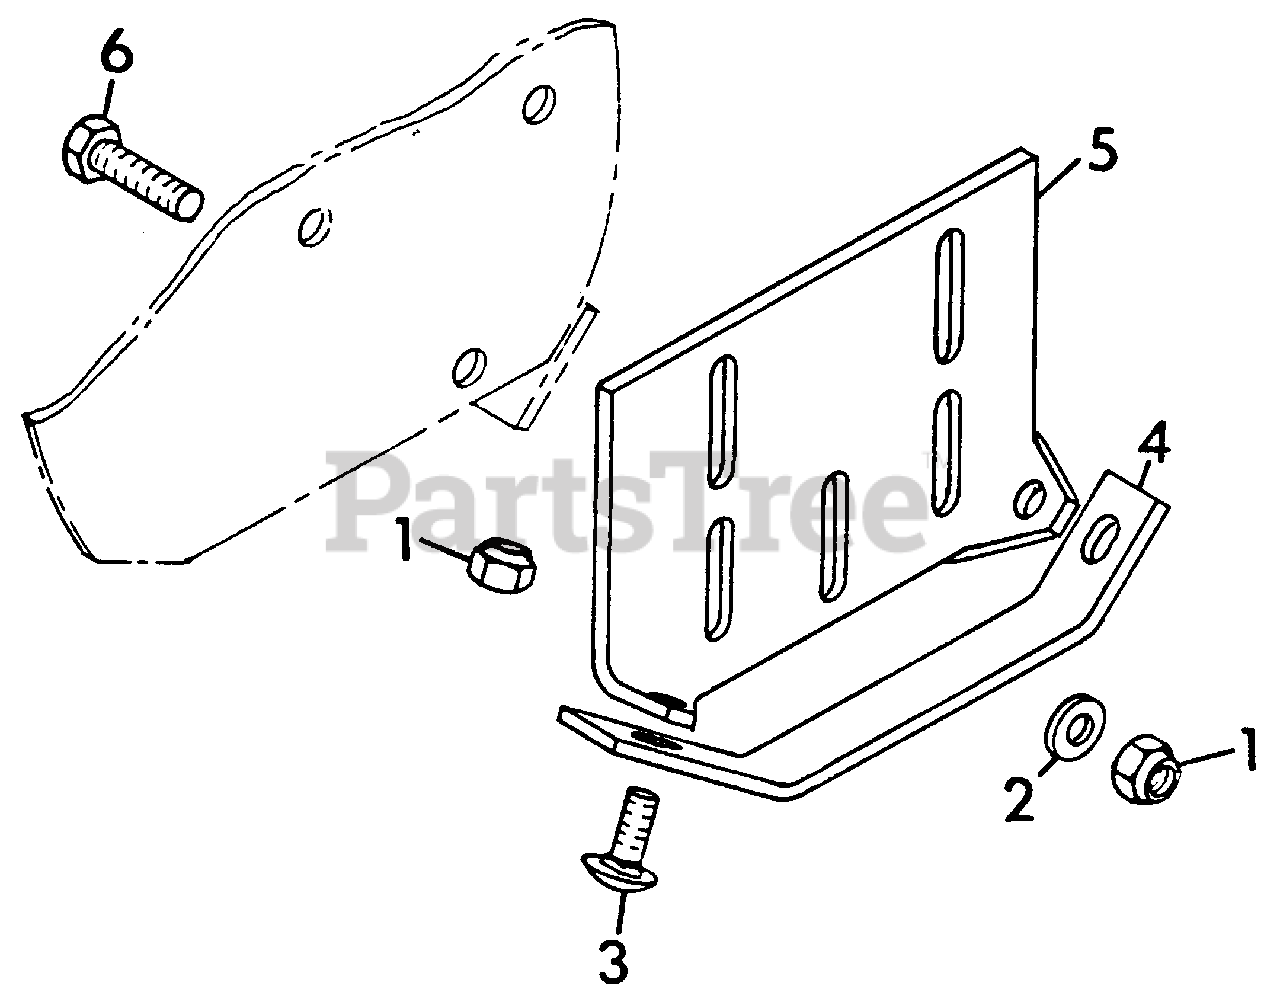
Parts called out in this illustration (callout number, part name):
1	NUT LOCK 3 8-16 WASHER
2	WASHER FLAT 406 X 812
3	BOLT 3 8-16 X 1 RD HD SQ NK
4	SKID
5	BRACE SKID
6	BOLT HEX 3/8-16X100
